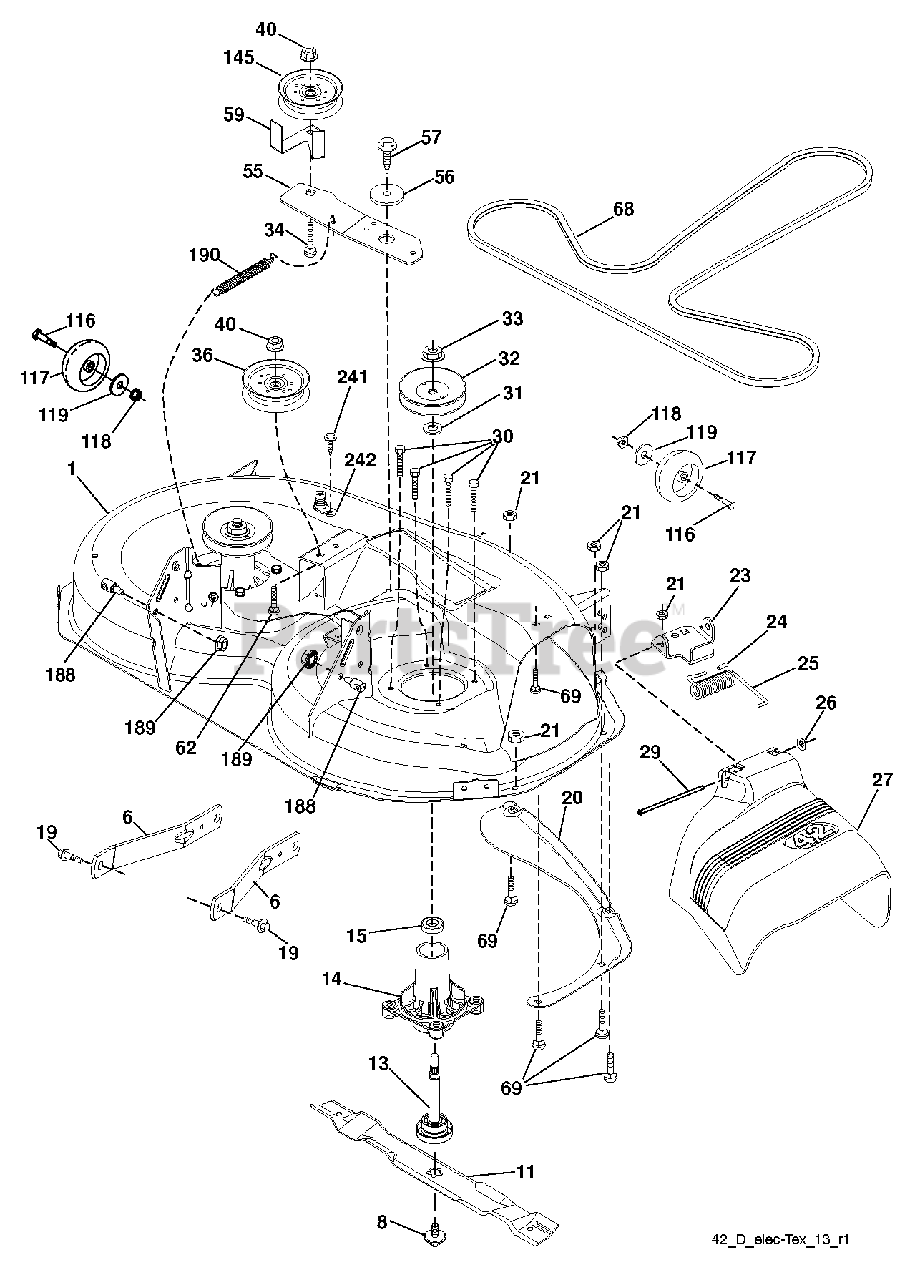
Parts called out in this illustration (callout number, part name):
1	DECK.WELDMENT.42"
6	ARM.SUSPENSION.MOWER.R
8	BOLT.WASHER.ASM.7/16-2
11	42" HI-LIFT BLADE
13	SHAFT.ASM.MDRL.N/GREASE.38
14	HOUSING MANDREL
19	BOLT.SHOULDER
20	BAFFLE.VORTEX
21	LOCKNUT
23	BRKT.DEFLECTOR.38"2005+
24	CAP-SLEEVE LT
25	SPRING.TORSION.DEFLECT
26	NUT PUSH M
27	SHIELD.DEFLECTOR.MOWER.42"BLAC
29	ROD.HINGE
30	SCREW, WASHER HEAD
31	WASHER.SPACER.MANDREL
32	PULLEY/MANDREL
33	NUT.FLANGE.LOCK.TOP
34	BOLT.3/8-16X1.50
36	PULLEY.IDLER.2006
40	NUT LOCK FLG 3/8-16 UNC
55	IDLER.ARM
56	SPACER.RETAINER
57	SCREW 3/8-16X1
59	GUARD, BELT
62	BOLT
68	BELT V SECONDARY
69	BOLT
117	WHEEL.GAGE.HALF.SPOKED
118	NUT LOCK FLG 3/8-16 UNC
119	WASHER
145	PULLEY.IDLER.48"PRIMARY
188	STUD.FASTNER.W/ANTI-ROTATE
189	NUT LOCK HEX FLANGE 5/16-18
190	SPRING.MOWER.DRIVE.ELECTRIC
242	PORT.WASHOUT
